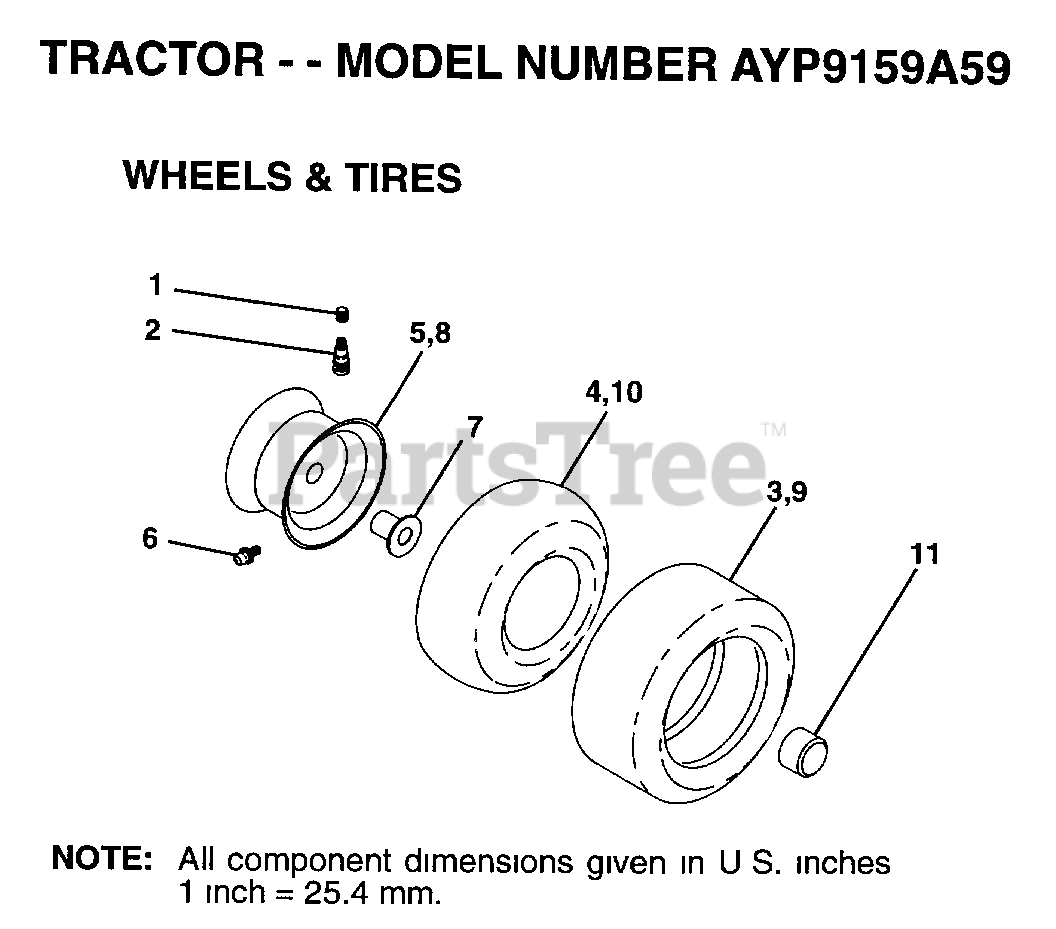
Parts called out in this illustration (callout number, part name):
1	VALVE CAP
2	VALVE STEM LT
4	TUBE.5.3/4.5/6
5	"RIM ASM 6"" FRT"
6	FITTING LT
7	"FLANGE, BEARING"
8	"RIM.ASM.8""REAR"
10	TUBE.18X9.5-8
11	HUB CAP
